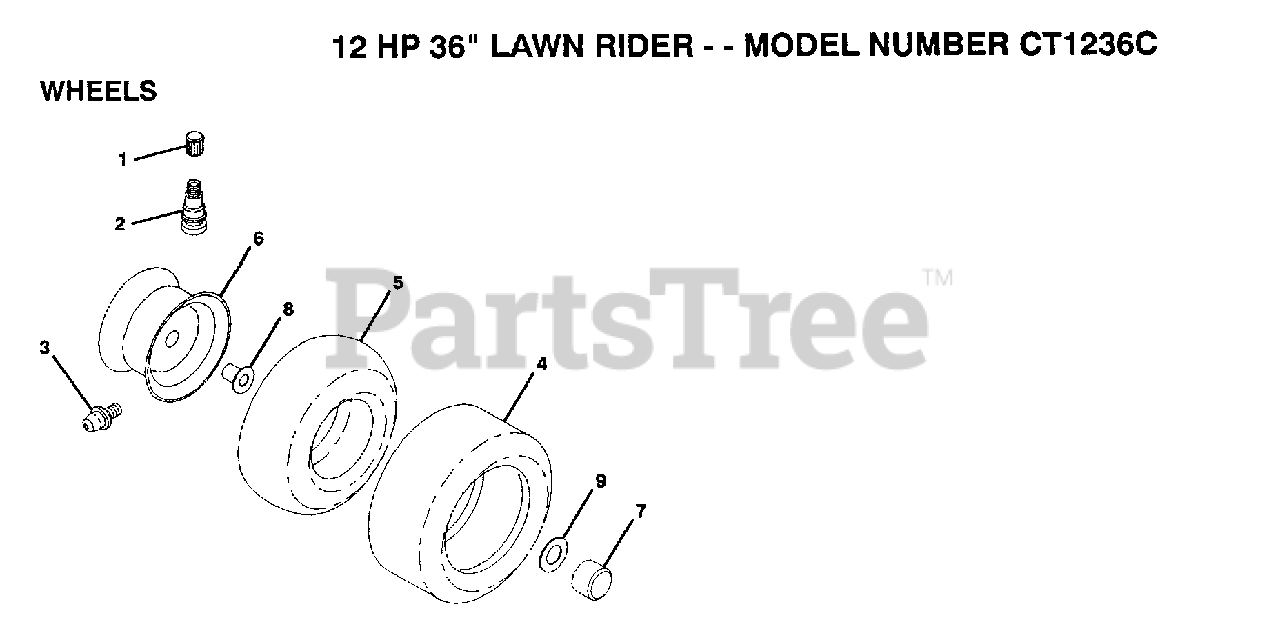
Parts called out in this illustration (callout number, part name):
1	VALVE CAP
2	VALVE STEM LT
3	FITTING LT
5	TUBE.5.3/4.5/6
7	HUB CAP
8	"FLANGE, BEARING"
9	WASHER
